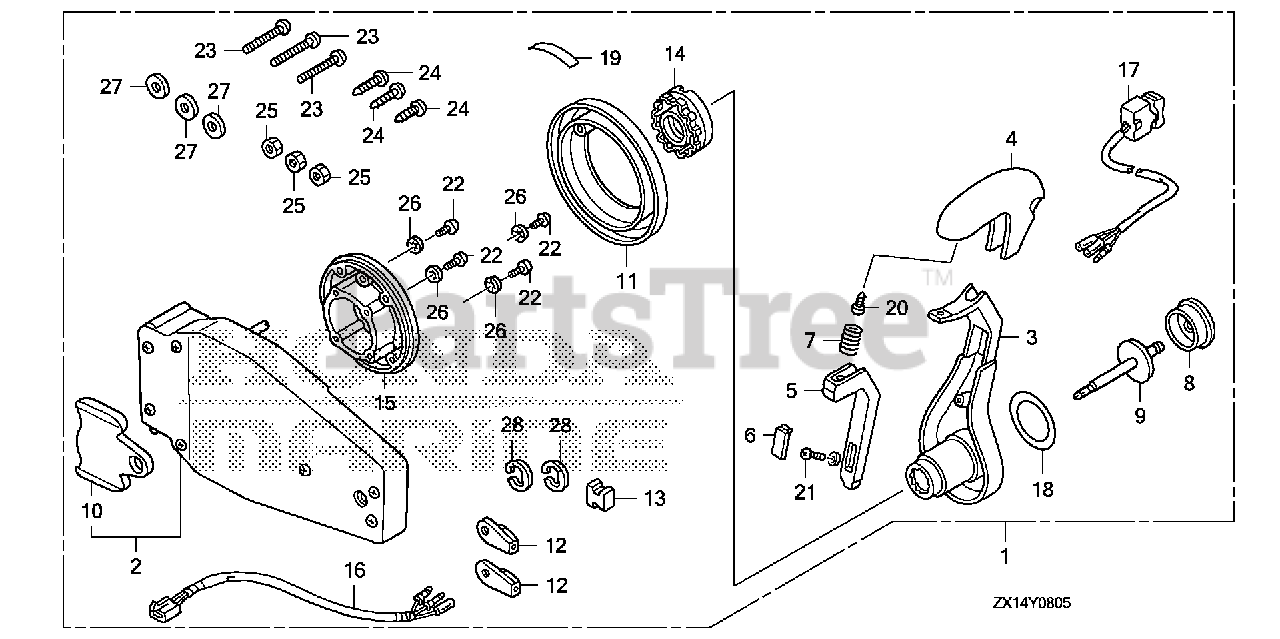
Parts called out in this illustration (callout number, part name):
1	BOX KIT, REMOTE CONTROL (FLUSH MOUNT)(L)
2	HOUSING ASSY., L. (INNER) (FLUSH MOUNT)
3	HANDLE, REMOTE CONTROL
4	COVER, GRIP
5	ARM, NEUTRAL LOCK
6	COVER, LOCK ARM
7	SPRING, NEUTRAL LOCK ARM
8	BUTTON, THROTTLE
9	SHAFT, THROTTLE BUTTON
10	PLATE, DWELL
11	COVER ASSY.
12	TERMINAL, CABLE
13	SPACER, CABLE CLAMP
14	HOLDER, NEUTRAL LOCK
15	BASE
16	SUB-HARNESS ASSY., POWER TRIM-TILT (C)
17	SWITCH ASSY., POWER TRIM-TILT (C)
18	MARK, HANDLE FLUSH MOUNT
19	MARK, FLUSH MOUNT
20	SCREW, PAN (5X16)
21	SCREW, TRUSS (4X12)
22	SCREW, PAN (5X30)
23	SCREW, PAN (6X35)
24	SCREW, TAPPING (6X30)
25	NUT, HEX. (6MM)
26	WASHER, LOCK (5MM)
27	WASHER, PLAIN (6MM)
28	E-RING (6MM)
